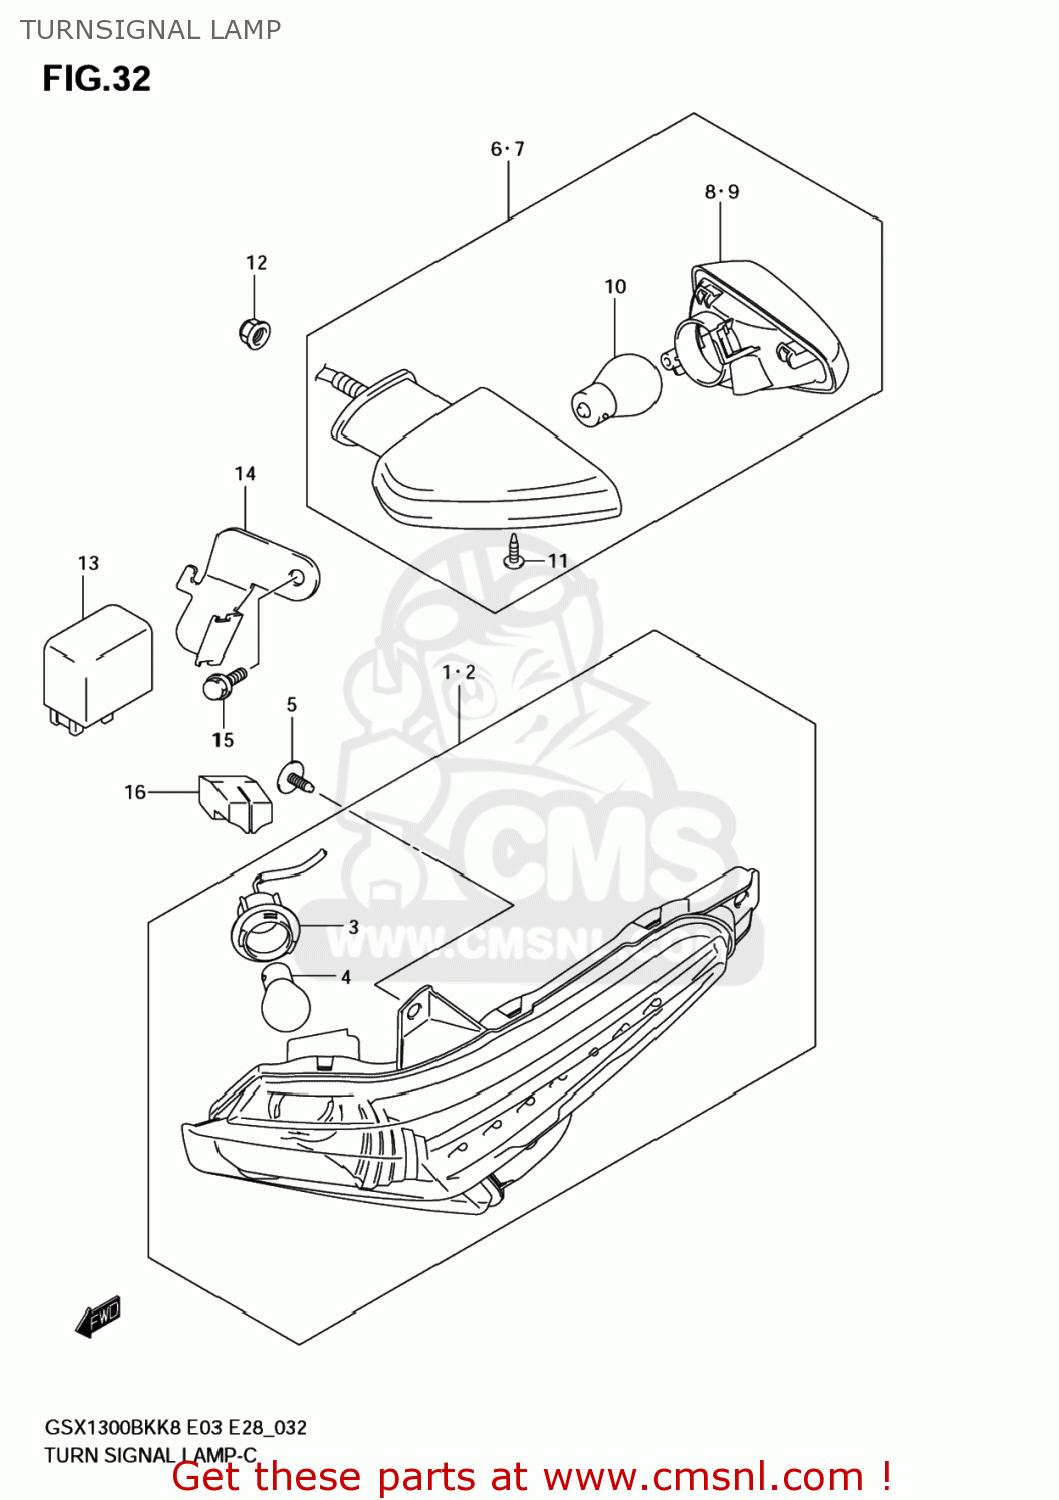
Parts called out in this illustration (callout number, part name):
1	LAMP ASSY,FR TURN SIGNAL,R
2	LAMP ASSY,FR TURN SIGNAL,L
3	SOCKET & CORD
4	BULB(12V21W,AMBER)
5	SCREW (5X20)
6	LAMP ASSY,RR TURNSIGNAL,R
7	LAMP ASSY,RR TURNSIGNAL,L
8	LAMP UNIT,R
9	LAMP UNIT,L
10	BULB(12V21W,AMBER)
11	SCREW
12	NUT
13	RELAY ASSY,TURNSIGNAL LAMP
14	BRACKET,TURNSIGNAL RELAY
15	BOLT
16	GUIDE,FUEL TANK COVER
